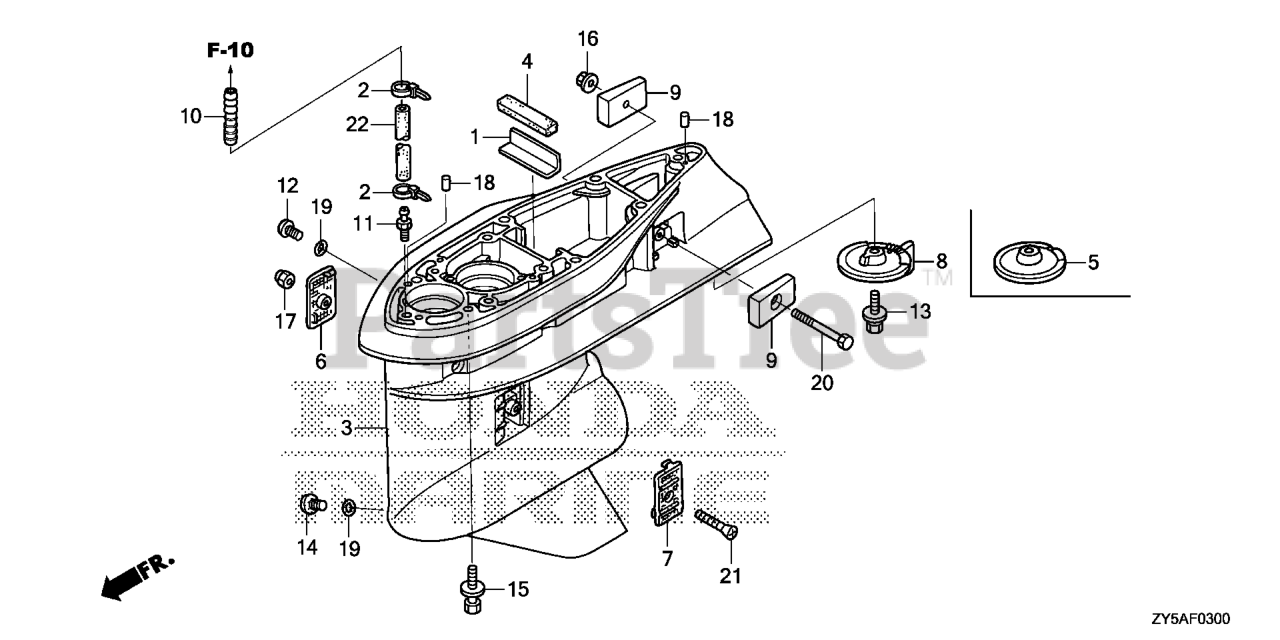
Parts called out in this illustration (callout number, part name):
1	PLATE, RUBBER SETTING
2	BAND, WIRE
3	CASE, GEAR *NHB14M* (AQUA MARINE SILVER METALLIC)
3	CASE,GEAR*NH565*
4	GROMMET, GEAR CASE
5	COVER, GEAR CASE *NHB14M* (AQUA MARINE SILVER METALLIC)
5	COVER, GEAR CASE *NH565* (GRAND PRIX WHITE)
6	SCREEN, R. WATER
7	SCREEN, L. WATER
9	METAL, ANODE
10	END, NIPPLE
11	NIPPLE, SENSOR
12	BOLT, OIL CHECK
13	BOLT-WASHER (10X32)
14	BOLT, DRAIN PLUG
15	BOLT-WASHER (10X40)
16	NUT, SELF-LOCK (6MM)
17	NUT, SELF-LOCK (5MM)
18	PIN, DOWEL (6X10)
19	O-RING (6.9X1.45)
20	BOLT, HEX. (6X50)
21	SCREW, OVAL (5X50)
22	BULK HOSE, VACUUM (5X3000) (5X250)
